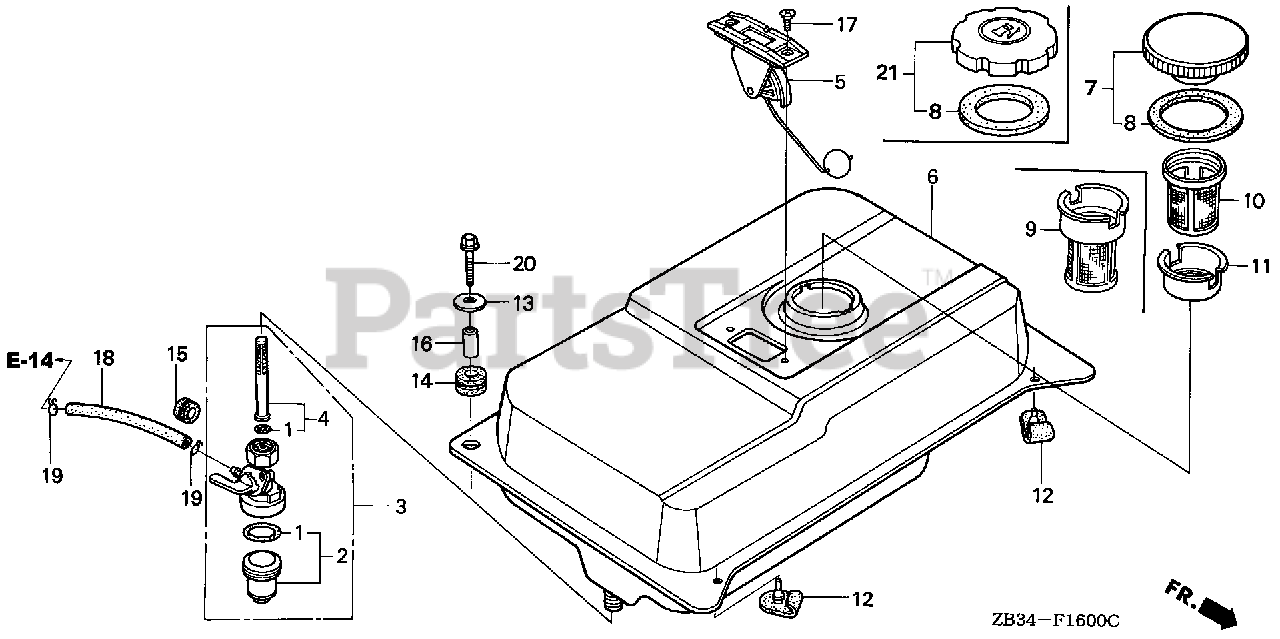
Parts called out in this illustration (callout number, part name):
1	GASKET SET, PETCOCK (CONTAINS 1 LARGE & 1 SMALL. USE AS NEEDED)
2	CUP, FUEL STRAINER
3	PETCOCK ASSY.
4	SCREEN SET
5	METER ASSY., FUEL
6	TANK, FUEL *R280* (POWER RED)
8	GASKET, FUEL FILLER CAP (39X58X3)
8	GASKET, FUEL FILLER CAP (39X62X3) (TOUYOUSYA)
9	FILTER, FUEL
12	RUBBER, TANK MOUNTING
13	WASHER, FLAT (20MM)
14	RUBBER, CONTROL BOX
15	RUBBER, FUEL (9X15X10)
15	RUBBER, FUEL (9X15X20)
16	COLLAR, CONTROL BOX
17	SCREW, FLAT (5X10)
18	BULK HOSE, FUEL (4.5X3000) (4.5X95)
19	CLIP, TUBE (B8)
20	BOLT, FLANGE (6X20)
21	CAP, FUEL FILLER (BLACK)
21	CAP, FUEL FILLER (CHROME PLATED)
21	CAP, FUEL FILLER (CHROME PLATED)(TOUYOUSYA)
